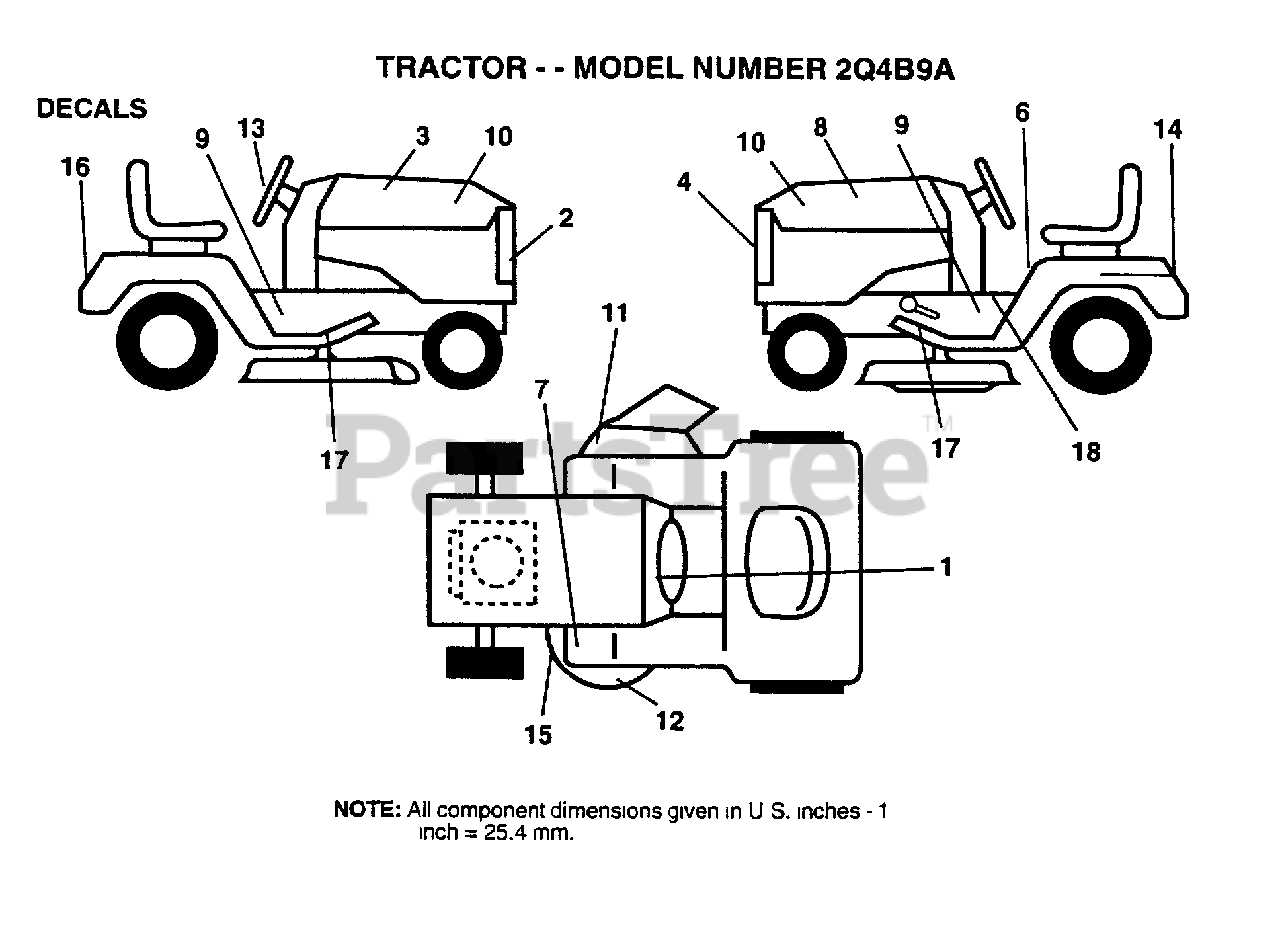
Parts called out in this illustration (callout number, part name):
1	DECAL.DASH.INSTR.
2	GRILL DECAL
3	DECAL HOOD RH RLY
6	DECAL CAUTION
7	DECAL T
8	DECAL HOOD LH RLY
9	CHASSIS DECAL
10	DECAL.INS.HD.RALL
11	"DECAL, WARNING"
13	"DECAL,STR WHL"
14	DECAL
15	DECAL
16	FENDER DECAL
17	"PAD,FOOTREST"
18	DECAL BRAK PARK
